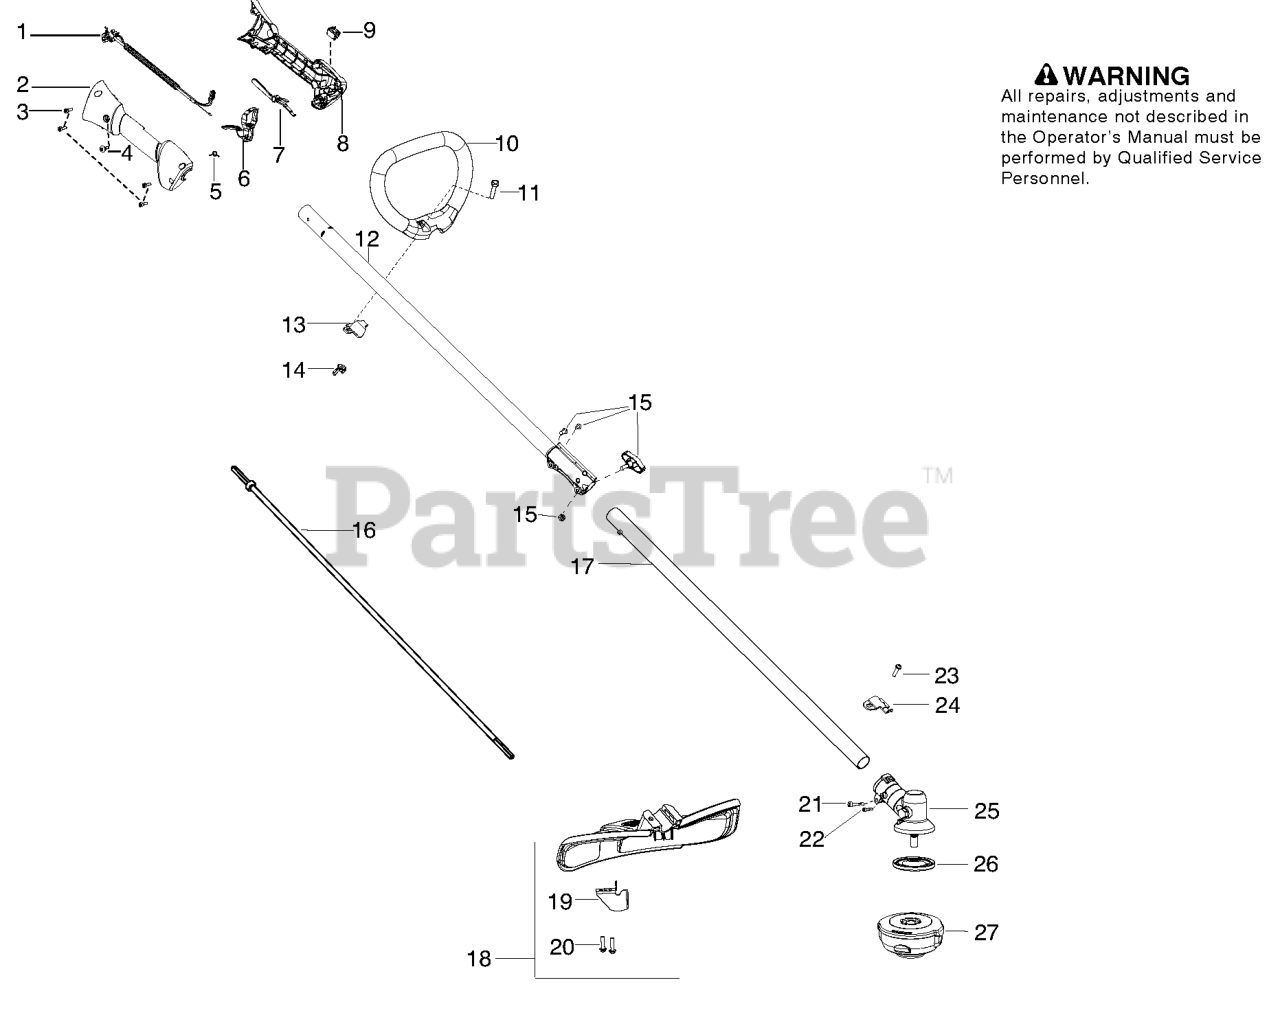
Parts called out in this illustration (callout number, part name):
1	Assy-Cable/Wire Harness
2	Housing-Throttle (RH)
3	Screw
4	Screw
5	SPRING TRIGGER
6	Trigger
7	Lockout-Throttle
8	Housing-Throttle (LH)
9	Kit-Switch
11	BOLT, TYPE 2
12	KIT UPPER SHAFT SILVER
13	CLAMP ASSIST HANDLE
14	WINGNUT, TYPE 2
15	ASSY COUPLER BLACK
17	KIT LOWER SHAFT
18	KIT COBI SHIELD
19	Limiter - Line
21	SCREW - CARB. ADAPTOR
23	SCREW 1/4-20 X 7/8 (TAP
24	BRACKET SHIELD STRAIGHT SHAFT
25	ASSY GEARBOX
26	DRIVE DISC
27	T25 TRIM HEAD 10MM LH
